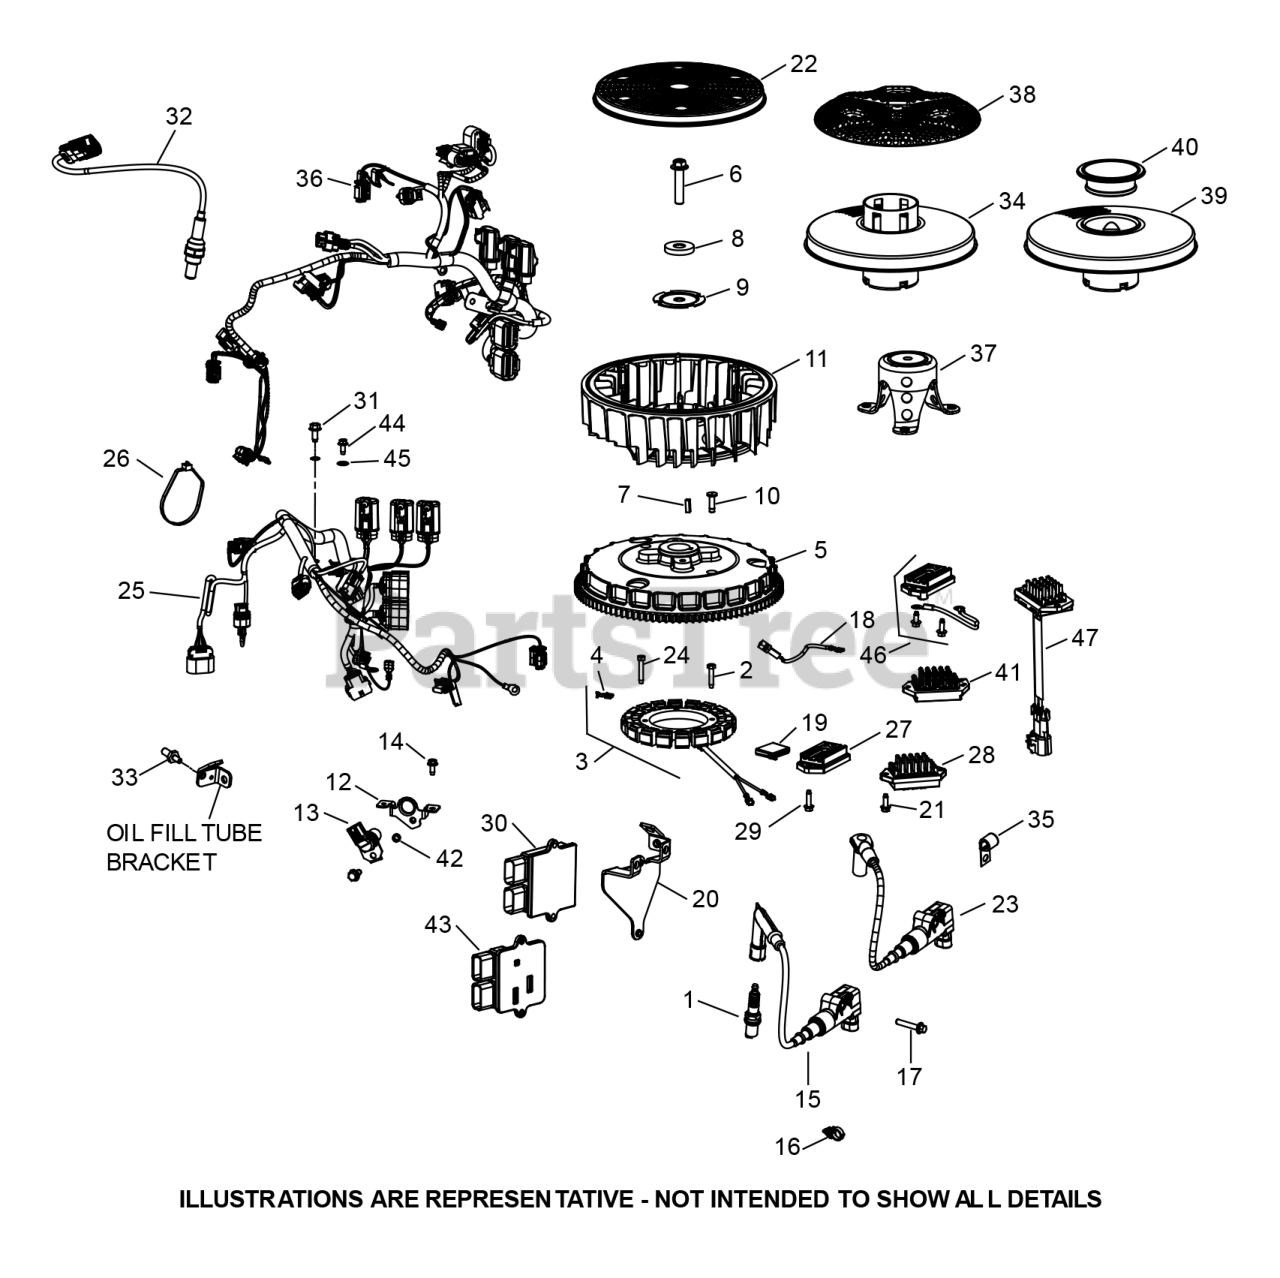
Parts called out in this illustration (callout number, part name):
2	THREAD FORMING SCREW
3	KIT-STATOR
5	FLYWHEEL ASSEMBLY
6	HEX FLANGE BOLT
12	SENSOR BRACKET
14	HEX SCREW FLANGE
16	CLIP-FUEL LINE
17	HEX FLANGE SCREW
18	REGULATOR RECTIFIER JUMPER LEAD
21	THREAD FORMING SCREW
23	COIL-IGNITION EFI
25	WIRING HARNESS ASSEMBLY
28	RECTIFIER REGULATOR
31	SCREW - CAPTIVE WASHER
39	GRASS SCREEN ASM
40	GRASS SCREEN CAP
